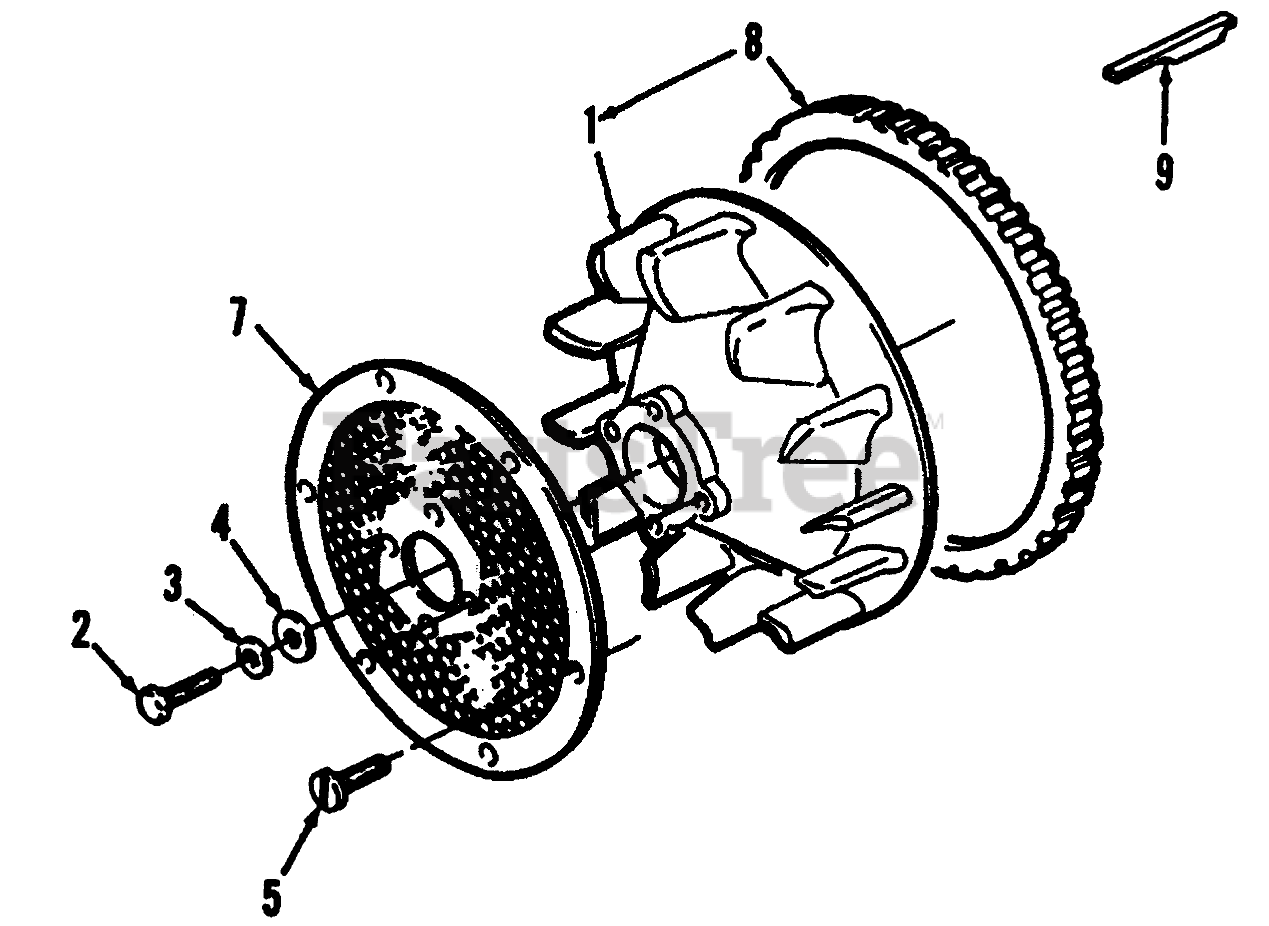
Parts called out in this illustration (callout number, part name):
1	Flywheel (Includes Ring Gear)
2	Screw
3	WASHER-FLAT
4	WASHER-FLAT
5	Bolt
7	Screen
8	Gear-Ring
9	Key
